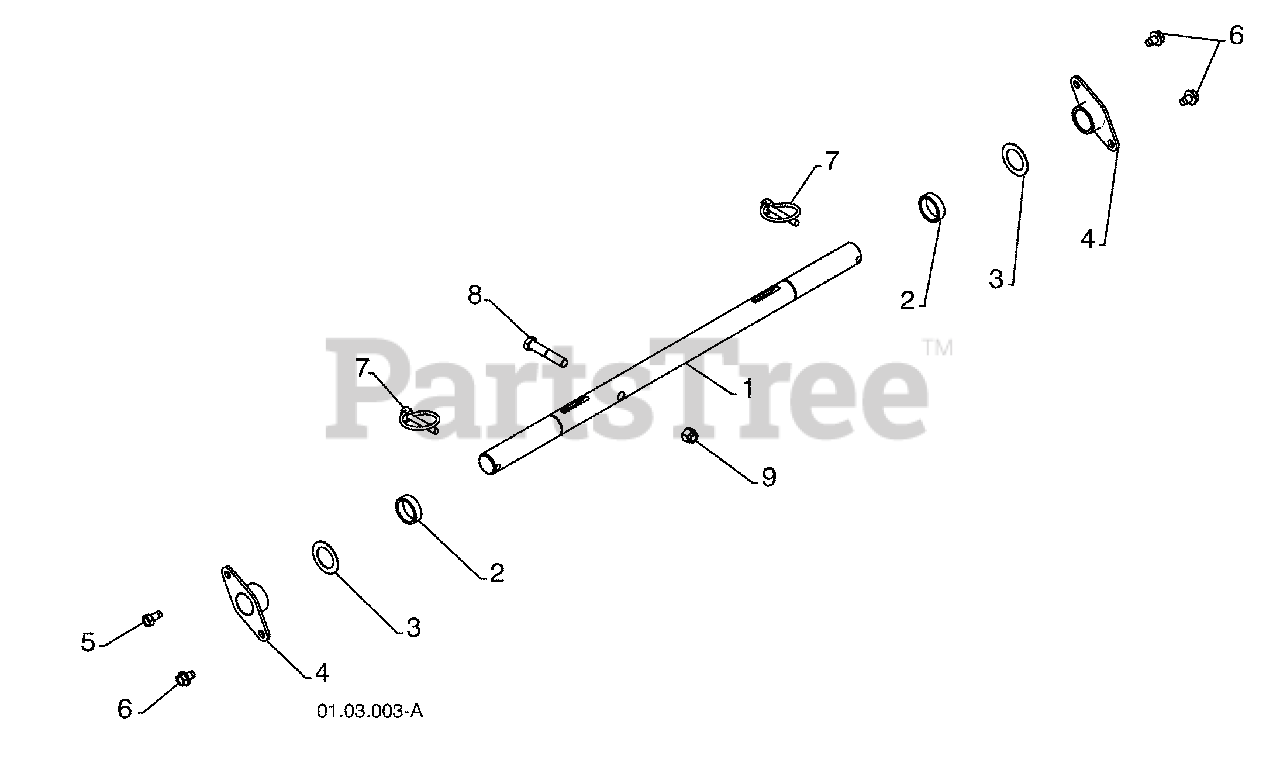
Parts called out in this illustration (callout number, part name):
1	AXLE SHAFT
3	THRUST WASHER
5	SCREW 5/16-18 X .625
6	BOLT 5/16-18 X .500
8	SCREW 3/8-16 X 2.00
9	NUT 3/8-16
